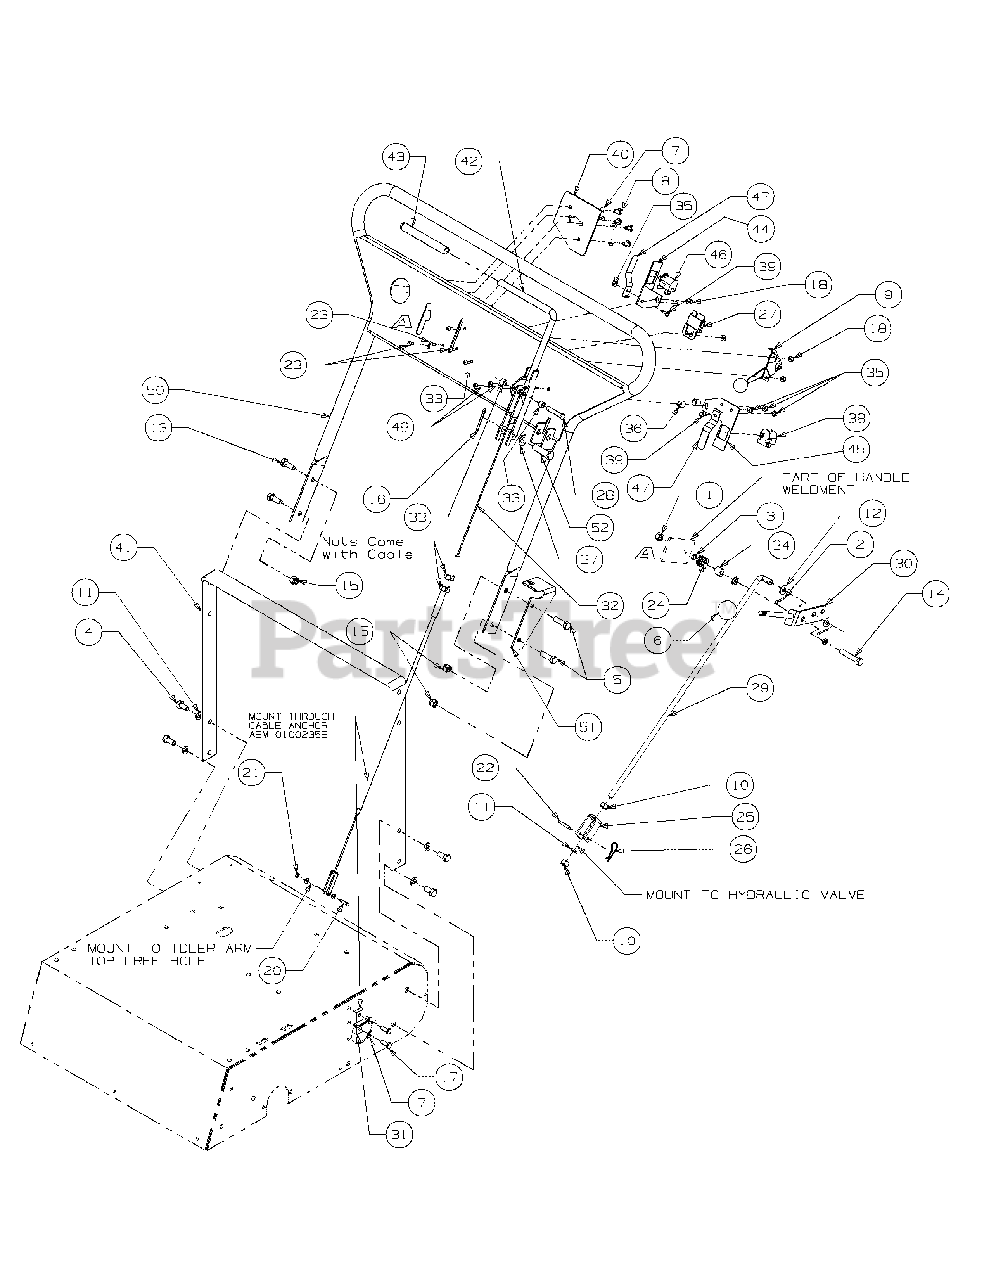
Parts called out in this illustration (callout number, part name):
1	Hex Nut, 3/8-16
2	Cotter Pin, 1/8 x 3/4
3	Flat Washer, 5/16
4	Hex Cap Screw, 3/8-16 x 3/4
5	Hex Cap Screw, 3/8-16 x 1 1/4
6	Knob, 1-3/8 x 1-19/64, 3/8-24
7	Lock Washer, 1/4
8	Hex Cap Screw, 1/4-20 x 1/2
9	Engine Throttle Cable
10	Hex Nut, 3/8-24
11	Lock Washer, 3/8
12	Flat Washer, 3/8
13	Hex Cap Screw, 3/8-16 x 1
14	Hex Cap Screw, 3/8-16 x 2
15	Lock Nut, Nylon Insert, 3/8-16
16	Cotter Pin, 5/32 x 1-1/2
17	Hex Cap Screw, 1/4-20, .75
18	Lock Nut, Nylon Insert, #10-32
20	Clevis Pin, 3/16 x 3/4
21	Flat Washer, 3/16
22	Clevis Pin, 3/16 x 1-1/4
23	Round Head Mach. Screw, 10-32 x 1/2
24	Spring, .850 OD x 1
25	Clevis, Shift
26	3/8"-1/2" Hair Pin
27	Module Volt Sensor
28	Clevis Pin, 5/16 x 1-5/8
29	Shift Lever Rod
30	Direction Control Lever
31	Cable Anchor Assembly
32	Control Cable Adjustment Blade
33	Turnbuckle Sleeve
34	Sleve Spring, 32/36/48
35	Nylon Lock Nut, #10-24
36	Spacer, .265 x .500 x .562
37	Flat Washer, .536 ID x .930 OD x .05
38	Snap Mounting Switch, NC
39	Hex Index Washer Screw, #10-24
40	Mounting Plate Valve
41	Lower Handle
42	Slicer Control Lever
43	Sleeve, 1/2" ID x 5.00" Long
44	Safety Switch Bracket
45	Slicer Safety Switch Bracket
46	Snap Mounting Switch, NO
47	Retainer Spring
48	Pan Head Machine Screw, 10-24 x 3/4
49	Wire Harness
50	Handle Assembly
51	Lower Handle Slicer Bracket
52	Clevis Pin, .500 DIA. x 1.75 LG.
